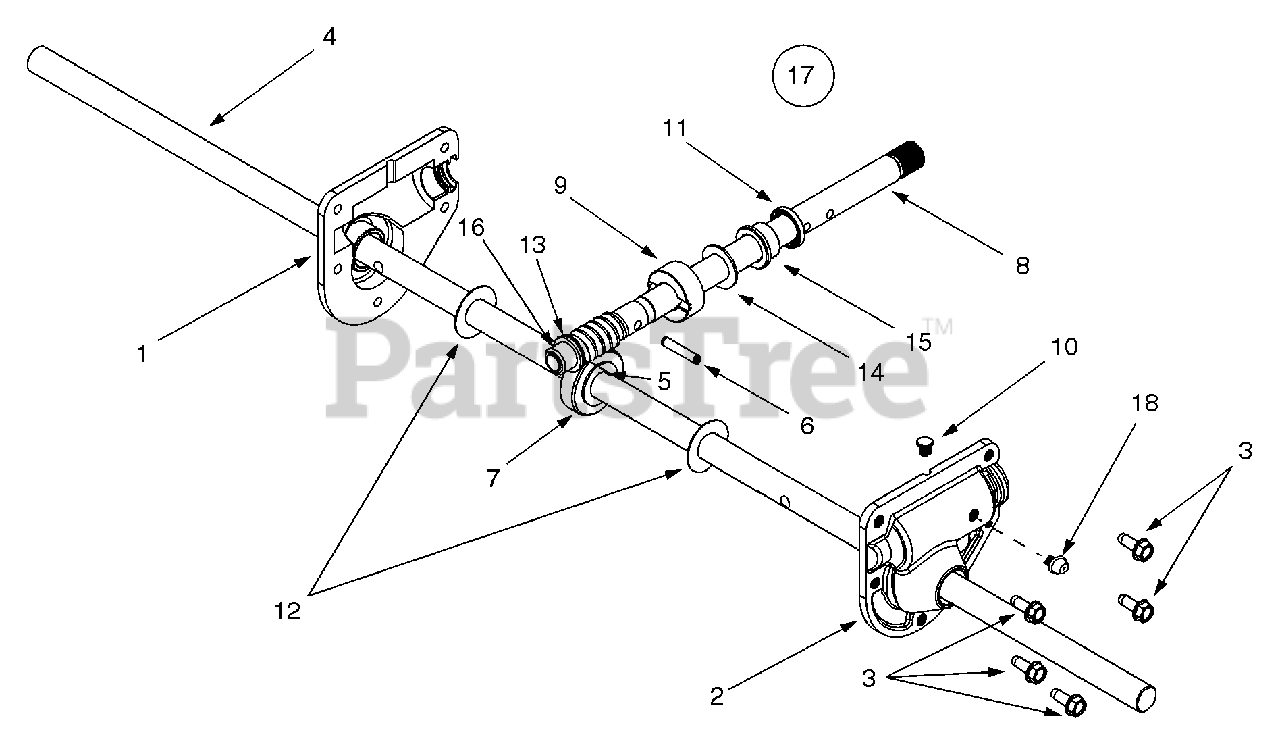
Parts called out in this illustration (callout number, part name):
1	RH Housing
2	LH Housing w/Fitting Hole
3	Self Tapping Screw, 1/4-20 x .75
4	Spiral Axle, 24"
5	Hi-Pro Key, 3/16 x 5/8
6	Spring Spirol Pin, .25 x 1.25
7	Worm Gear, 20-tooth
8	Worm Shaft
9	Thrust Collar
10	Grease Plug
11	Grease Seal
12	Flat Washer, .76 x 1.5 x .030
13	Flat Washer, .508 x 1.0 x .020
14	Flat Washer, .76 x 1.5 x .060
15	Flange Bearing, .75 x 1.0 x .59
16	Flange Bearing, .503 ID x .75 OD
17	Gear Assembly Complete, 24", w/ Fitting
18	Grease Fitting, 3/16" Drive
